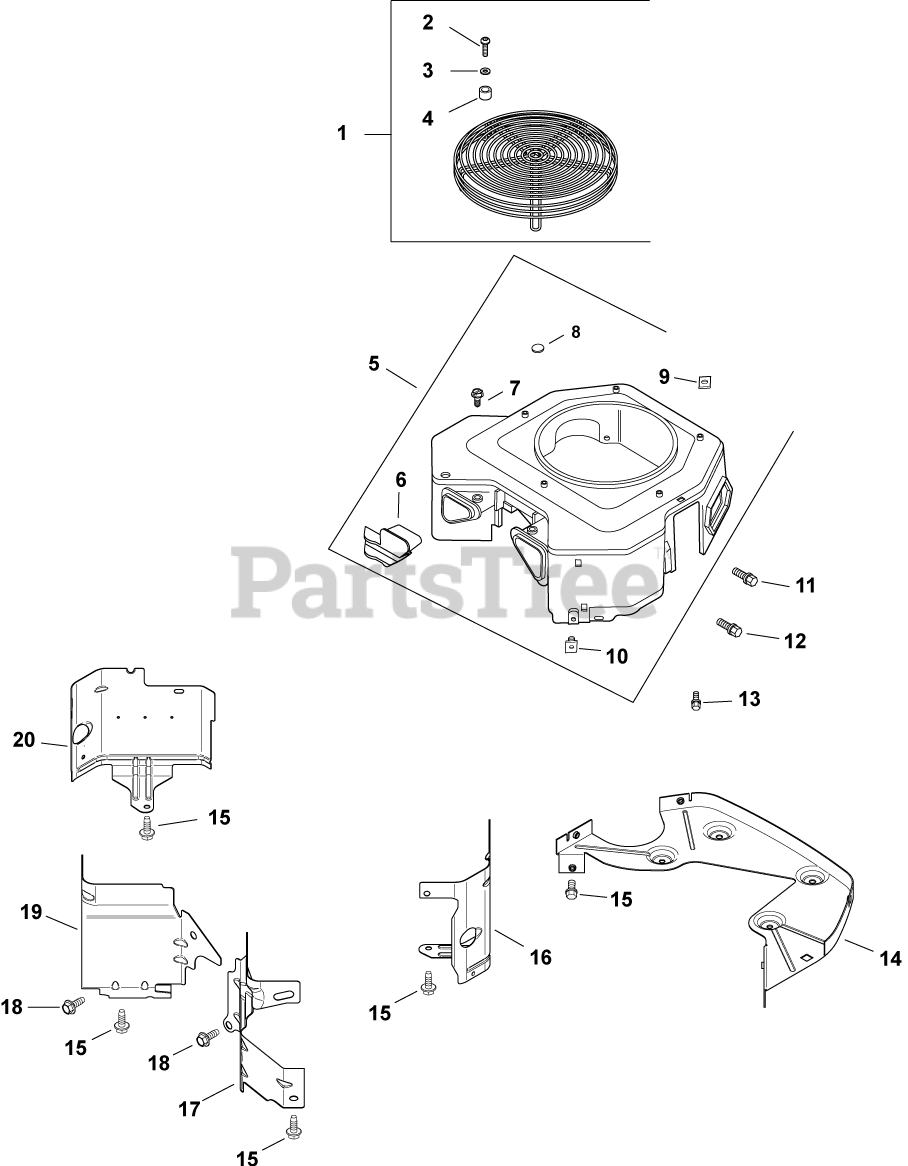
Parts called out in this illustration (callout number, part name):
1	KIT, GUARD
2	SCREW, PAN HEAD-USE 25 086 160-S
3	WASHER, FLAT 7/32"
4	SPACER USE 25 112 30-S
5	KIT, BLOWER HOUSING ASSEMBLY USE 24 027 493-S
6	COVER, BLOWER HOUSING-USE 24 096 119-S
7	SCREW, WSH HD TAP #8-18X1/2"
8	PLUG, BUTTON 9/16
9	NUT, PLASTIC (KM)-USE 25 100 37-S
10	NUT, PLASTIC
11	SCREW - USE M-545016-S
12	SCREW,FLG THD FRM M5X0.8X16-(#25086398S)
13	SCREW, FLG THD FRM M5X.8X20-(#25086399S)
14	PLATE, BACKING-USE 24 146 59-S
15	SCREW,FLG THD FRM M6X1.0X16-(#25086397S)
16	BAFFLE, LEFT BARREL -USE 24 063 88-S
17	BAFFLE, VALLEY #2 SIDE-USE 24 063 94-S
18	SCREW, FLG THD FRM M5X.8X10
19	BAFFLE, VALLEY (CV)-USE 24 063 93-S
20	KIT, CYL BAFFEL #1 SIDE
2508643-S	SCREW, SKT SET #10-24X1/4"
4103710-S	NAMEPLATE, SERVICE
